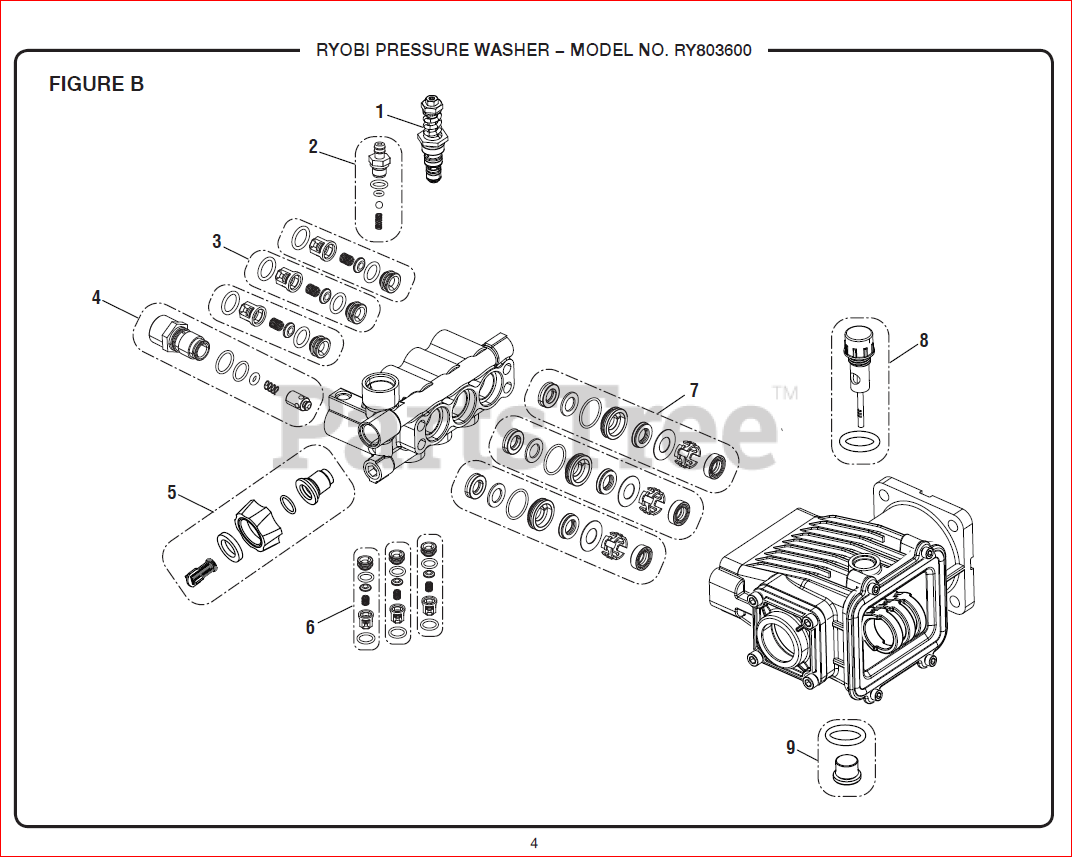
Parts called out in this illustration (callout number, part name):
1	Unloader Assembly
2	Soap Injector
3	Inlet Valve Kit
4	Outlet Connector
5	Inlet Assembly
6	Outlet Valve Kit
7	Pressure Seal
8	Vent Plug Kit
9	Oil Plug Kit
